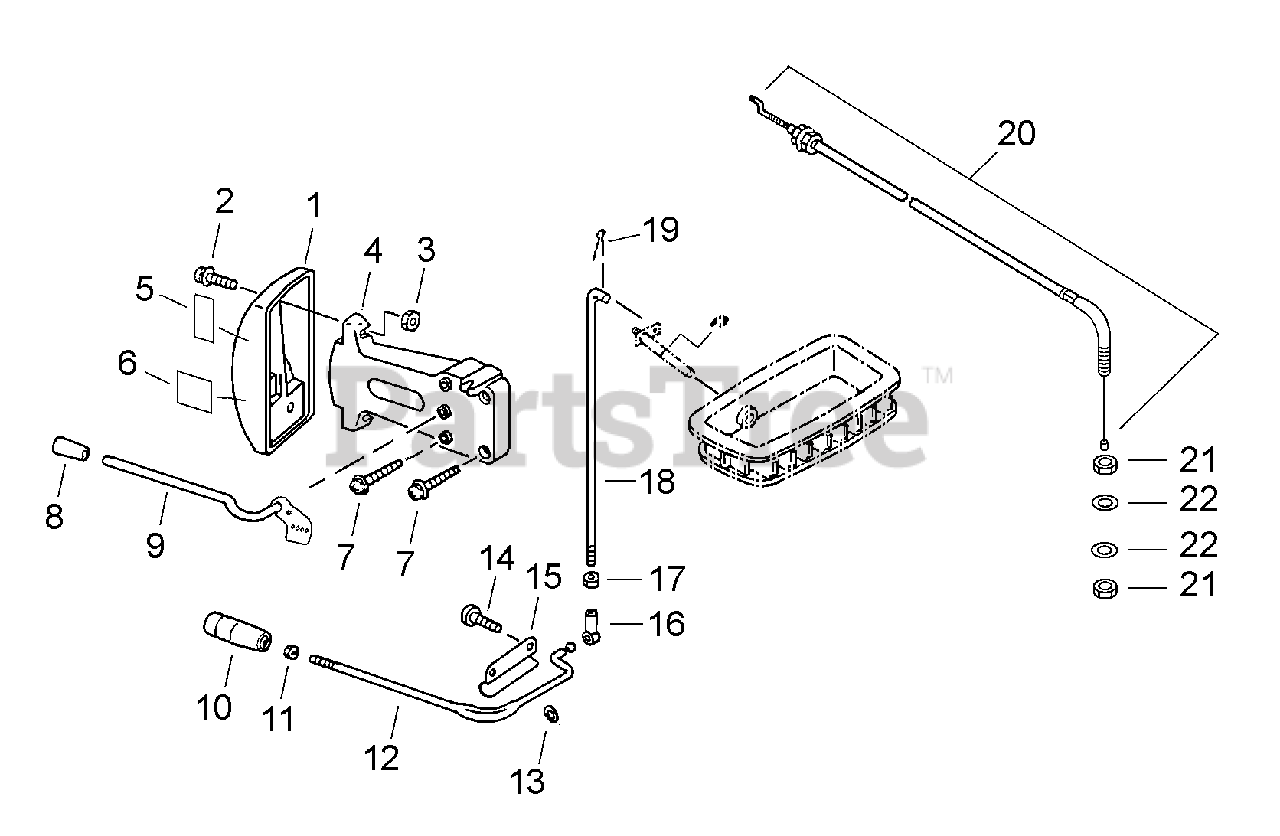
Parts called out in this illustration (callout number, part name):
1	DIAL, METERING
2	SCREW 5×25 SUS
4	BRACKET, DIAL
5	LABEL, THROTTLE
6	LABEL, STOP
7	SCREW 5×25 SUS
8	KNOB, THROTTLE CONTROL
9	LEVER, THROTTLE CONTROL
10	KNOB, SHUTTER CONTROL
12	LEVER, SHUTTER CONTROL
13	WASHER 8.5×16×1.2
14	SCREW 5×14 SUS
15	BRACKET, CONTROL LEVER
16	CONNECTOR, ROD
17	NUT M5
18	ROD, CONTROL LEVER
19	PIN, COTTER 1.8×18
20	CABLE, THROTTLE
21	NUT 6 MM
22	WASHER 6.5×11.5×0.8
